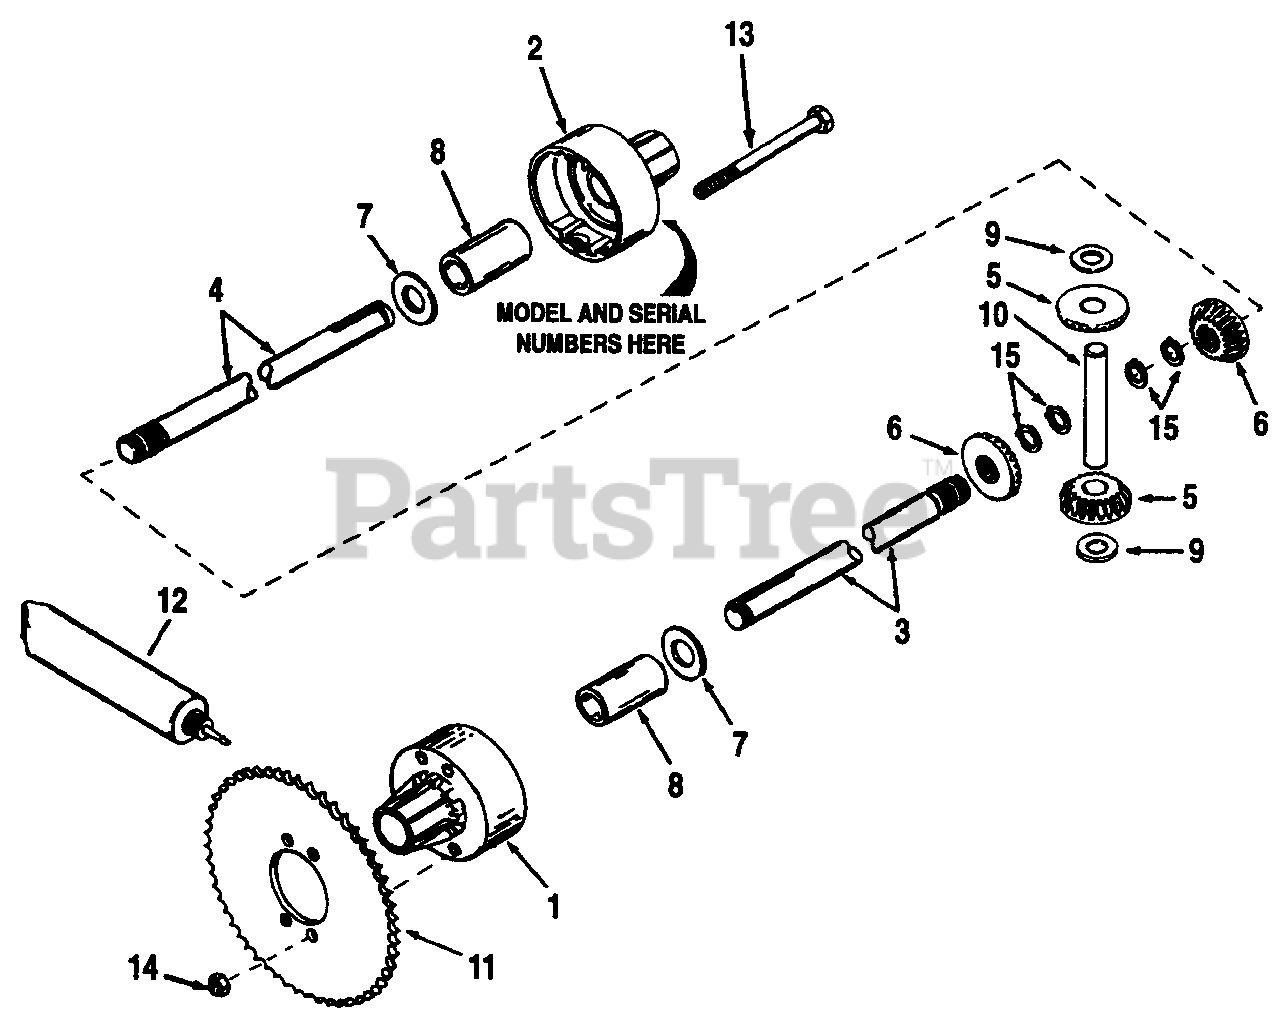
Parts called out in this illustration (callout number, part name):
1	CARRIER, Differential (Incl. qty. 1, Ref. No. 8)
2	CARRIER, Differential (Incl. qty. 1, Ref. No. 8)
3	AXLE, 20-3/16" long
4	AXLE, 8-1/32" long
5	BEVEL PINION (16 teeth)
6	BEVEL GEAR (16 teeth)
10	DRIVE PIN
11	SPROCKET, Optional (45 teeth-7.389" O.D.)
12	GREASE, Bentonite, 32 oz. Bottle
13	SCREW, 5/16-18 x 3-3/4
14	LOCKNUT, 5/16-18
15	RETAINING RING (Pkg. of 2)
